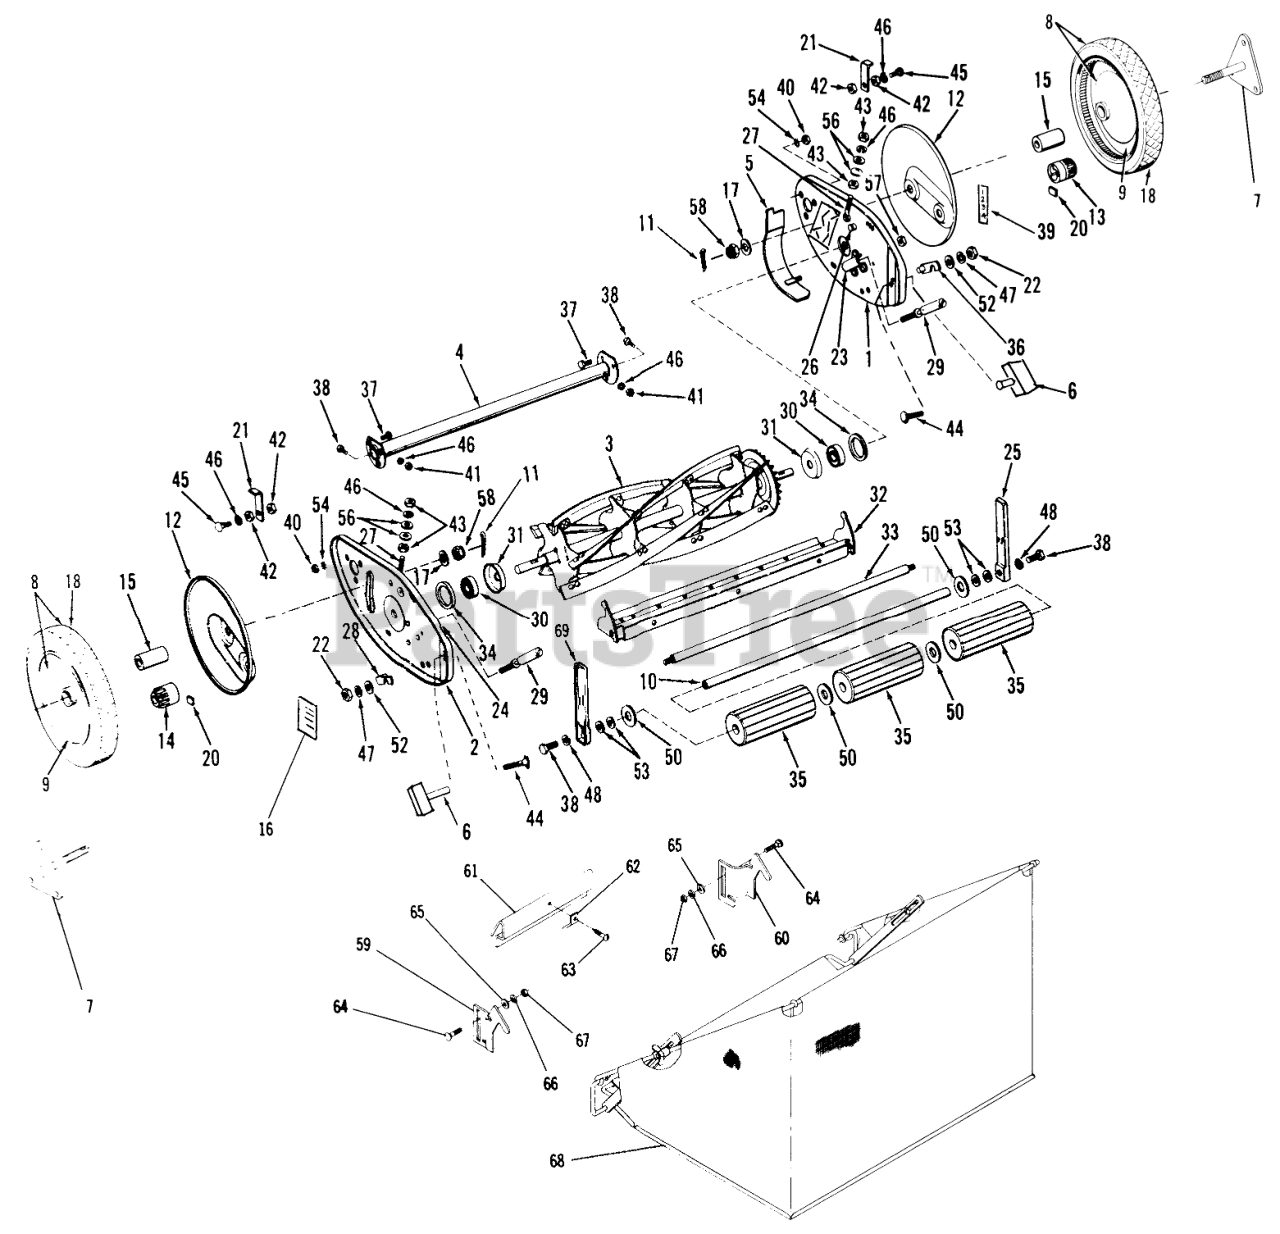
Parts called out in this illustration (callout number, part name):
1	Frame, R.H. Side
2	Frame, L.H. Side
3	Reel Assembly, 5 Blade, w/Sprocket
4	Tube, Front Cross
5	Guard, Reel Sprocket
6	Knob, Roller Adj.
7	Knock-Off Spinner Ass-y.
8	Wheel w/Tire
9	Wheel w/O Tire
10	Shaft, Rear Roller
11	Cotter Pin
12	Shield, Dust
13	Pinion, Drive, R.H.
14	Pinion, Drive, L.H.
15	Shaft, Wheel
16	Decal, Height Inst.
17	Lockwasher, 1/2 Ext.
18	Tire, Diamond Tread
20	Pawl, Pinion Drive
21	Bracket, Handle Stop
22	3/8-16 Jam Nut
23	Case, R.H. Adjusting Screw
24	Case, L.H. Adjusting Screw
25	Bracket Rear Roller R.H.
26	Stud, Handle
27	Screw, Deck Adjusting
28	Plate, L.H. Mounting Plate
29	Screw, Cutter Bar Adjusting
30	Bearing, Reel Shaft
31	Slinger, Dirt
32	Bar, Cutter
33	Rod, Tie
34	Washer, Seal, Reel Bearing Felt
35	Roller, Rear
36	Plate, R.H. Mounting Pin
37	Bolt, 1/4-x 1/2
38	Bolt Hex 5/16-18
39	Decal, Roller Adj.
40	Nut 1/4-20
41	Nut, 5/16-18 Hex
42	Nut 5/16-18 Jam
43	Nut, 5/16-24 Hex Jam
44	Bolt-5/16-18 x 1 1/2
45	Bolt-Carriage 5/16-18
46	Lockwasher
47	Lockwasher 3/8
48	Lockwasher, 5/16
50	Washer-Flat
52	Washer
53	Washer
54	Lockwasher, 1/4
56	Washer, 5/16 Flat
57	Nut, 5/16-18 Hex Conelock
58	Nut, 1/2-13 Adjustment (Special)
59	Bracket, L.H. Catcher
60	Bracket, R.H. Catcher
61	Deflector, Grass
62	Clip
63	Screw #10 x 1/2 Type A
64	Bolt, Carriage S.N. 5/16-18 x 1
65	Washer
66	Lockwasher
67	Nut, 5/16-18 Hex
68	Grass Catcher Ass-y.
69	Bracket, Rear Roller L.H.
